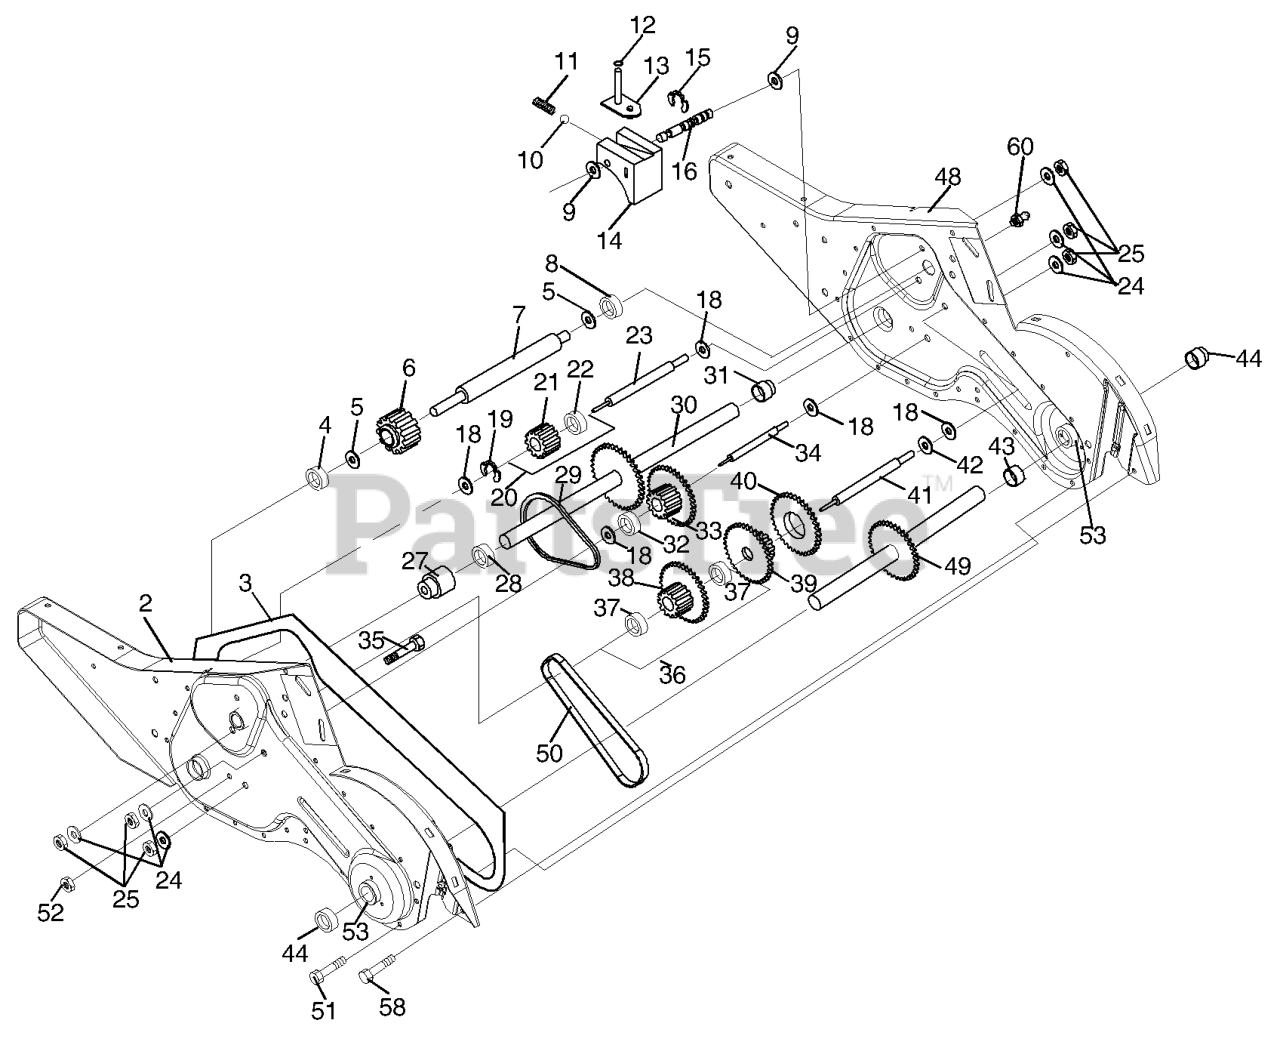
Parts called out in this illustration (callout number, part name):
1	TRANSMISSION ASM.
2	GEARCASE.ASM.CRT.LH.W/BEARING
3	GASKET
4	NEEDLE BRNG LT
5	THRUST WASHER
6	GEAR.PINION.INPUT
7	SHAFT.INPUT."D".TILLER
8	BEARING TI
9	WASHER, SEAL (2 2)
10	STEEL BALL KIT
11	SPRING-SHIFT CRT
13	BRACKET ASM.SHIFT.CRT
14	SHIFT FORK TI
16	SHAFT.SHIFTER.TILLER
20	GEAR ASSY CRT
21	GEAR-REV IDLR CRT
22	NEEDLE BEARING TI
24	LOCKWASHER
25	NUT.ASF.HEX.7/16
27	BEARING, SHAFT LH CRT
30	GROUND SHAFT ASS'Y
31	BEARING, SHAFT RH CRT
33	SPRCKT 8 GEAR CRT
34	SHAFT.SECONDARY.REDUCTION.CRT
35	SCRW WHIZ LOK CRT
36	SPROCKET.ASM.W/BEARING.TILLER
37	BEARING
38	SPROCKET, TINE
41	SHAFT.REDUCTION.TILLER
42	BRNG RACE T
44	SEAL ASM, OIL
48	GEARCASE.ASM.CRT.RH.W/BEARING
49	TINE SHAFT
50	CHAIN.TILLER
51	SCREW
52	NUT
53	KIT.BEARING.TILLER.
58	BOLT SHOULDER 1/4-20 UNC X.875
60	FITTING.GREASE.TAPERED
